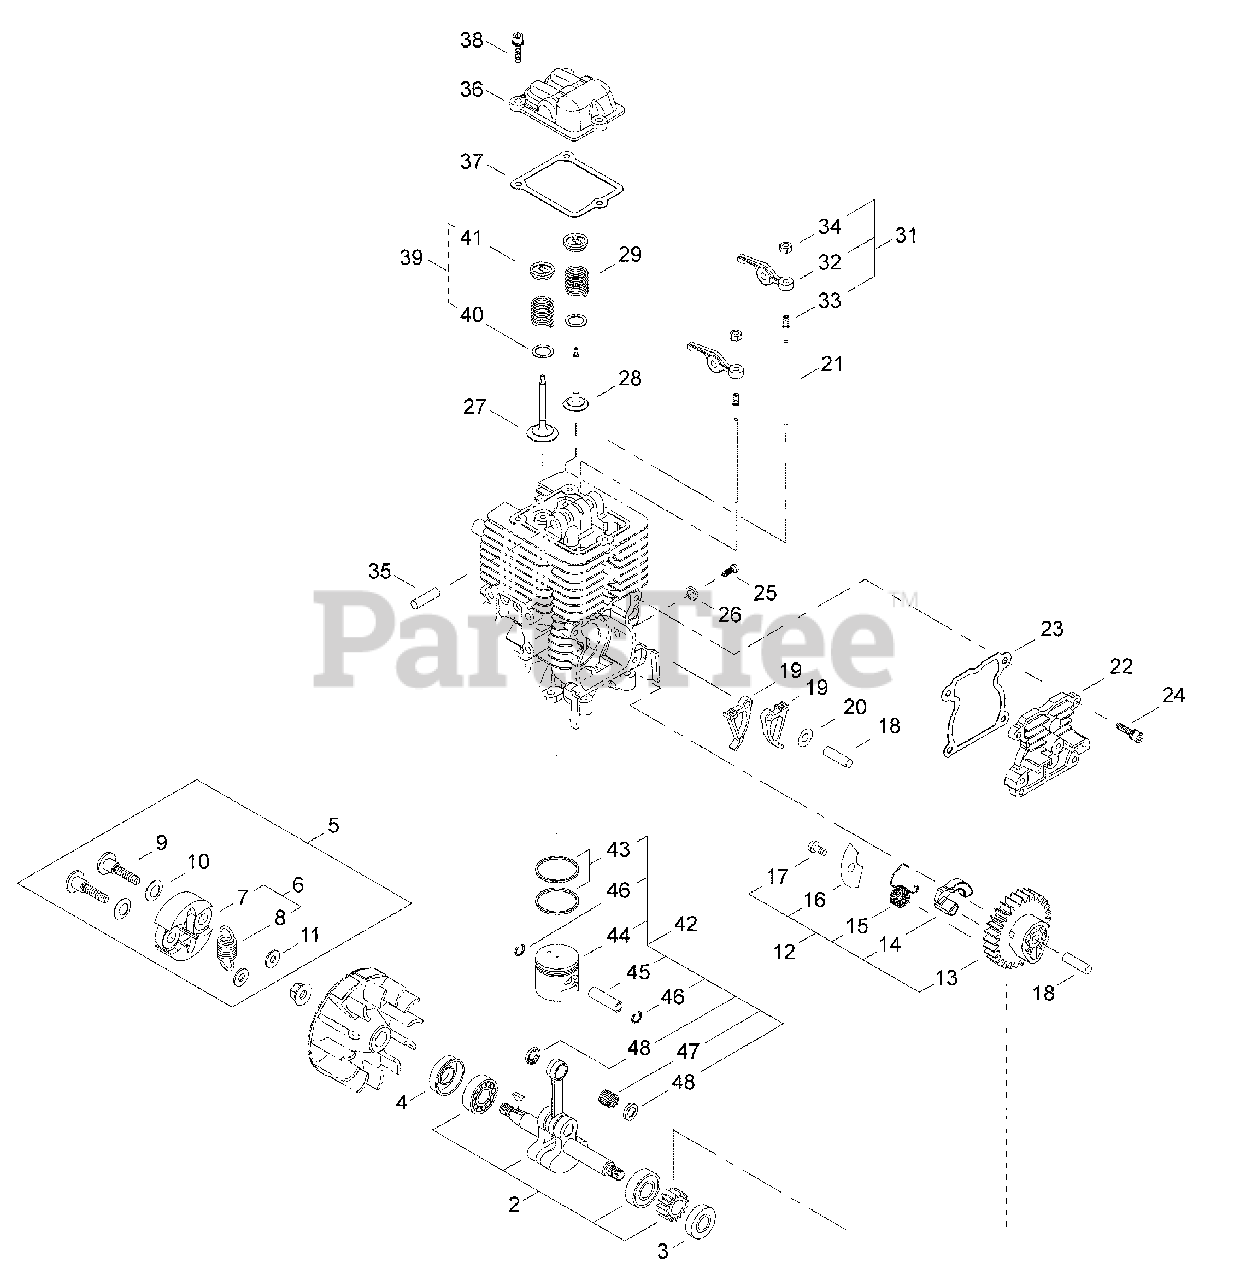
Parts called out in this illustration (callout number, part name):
2	CRANKSHAFT ASSY
3	SEAL, OIL - 12
4	SEAL, OIL
5	CLUTCH SHOE ASSY
6	CLUTCH SHOE ASSY
7	SHOE, CLUTCH
8	SPRING, CLUTCH
9	BOLT, CLUTCH
10	WASHER - SPRING
11	WASHER - 6
12	CAM GEAR ASSY
13	GEAR, CAM
14	WEIGHT
15	SPRING
16	COVER, PLATE
17	SCREW - 4X6 -- TAPPING
18	PIN - LOCATING
19	FOLLOWER, CAM
20	WASHER - 5
21	PUSHROD
22	COVER, CAM GEAR
23	GASKET
24	SCREW - 4X14
25	SCREW - 5
26	WASHER
27	VALVE, INTAKE
28	VALVE, EXHAUST
29	SPRING, VALVE
31	ROCKER ARM ASSY
32	ARM, ROCKER
33	SCREW, ADJUST
34	LOCKNUT, ADJUSTER
35	SHAFT, ROCKER ARM - 5X37.8
36	COVER, ROCKER ARM
37	GASKET
38	SCREW - 4X14
39	VALVE RETAINER ASSY
40	WASHER, VALVE - 9
41	RETAINER, VALVE
42	PISTON KIT
43	RING, PISTON
44	PISTON
45	PIN, PISTON
46	RING, RETAINING
47	BEARING, NEEDLE
48	WASHER, THRUST - 10
